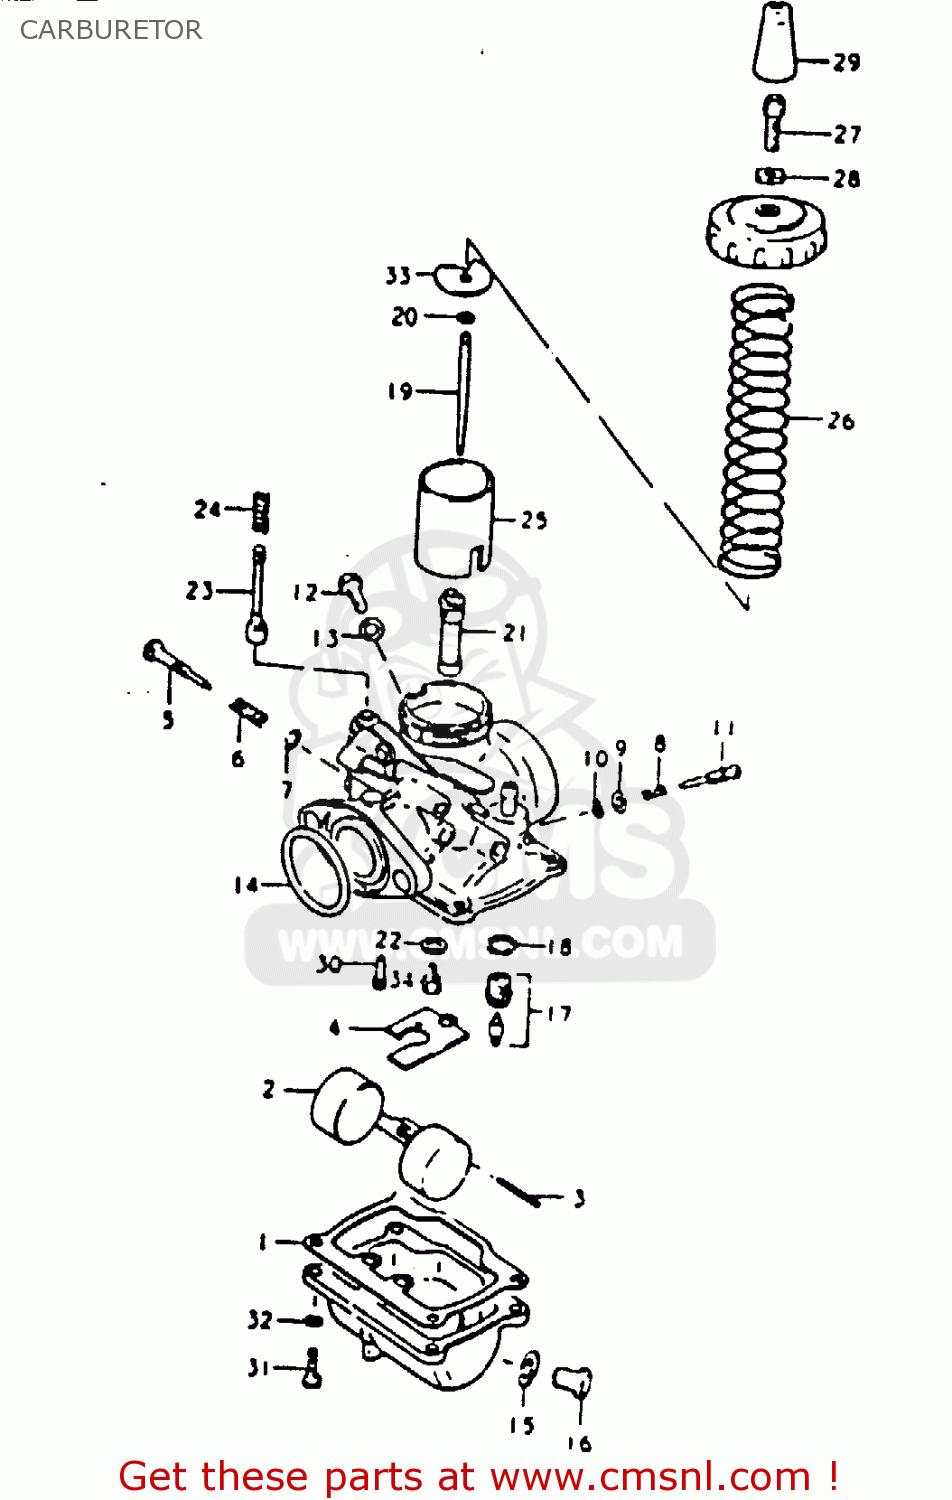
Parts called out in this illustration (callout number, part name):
1	GASKET,FLOAT CHAMBER (NAS)
2	FLOAT
3	PIN,FLOAT
4	PLATE
5	SCREW,THROTTLE STOP
6	SPRING,PILOT
7	O RING
8	SPRING
9	WASHER,PILOT AIR SCREW
10	O RING
11	SCREW,PILOT AIR
12	BOLT
13	GASKET,THRO VALVE INSPECTION (NAS)
14	O RING
15	GASKET,DRAIN,PLUG (NAS)
16	PLUG
17	VALVE ASSEMBLY,NEEDLE
18	GASKET,VALVE SEAT (NAS)
19	NEEDLE,JET
20	CLIP
21	22
22	WASHER
23	VALVE,STARTER
24	SPRING
25	VALVE,THROTTLE
26	SPRING,THROTTLE VALVE
27	ADJUSTER,CABLE
28	NUT
29	CAP
30	JET
31	SCREW
32	LOCK WASHER
33	SEAT,THROTTLE VALVE SPRING
34	JET,MAIN 85
